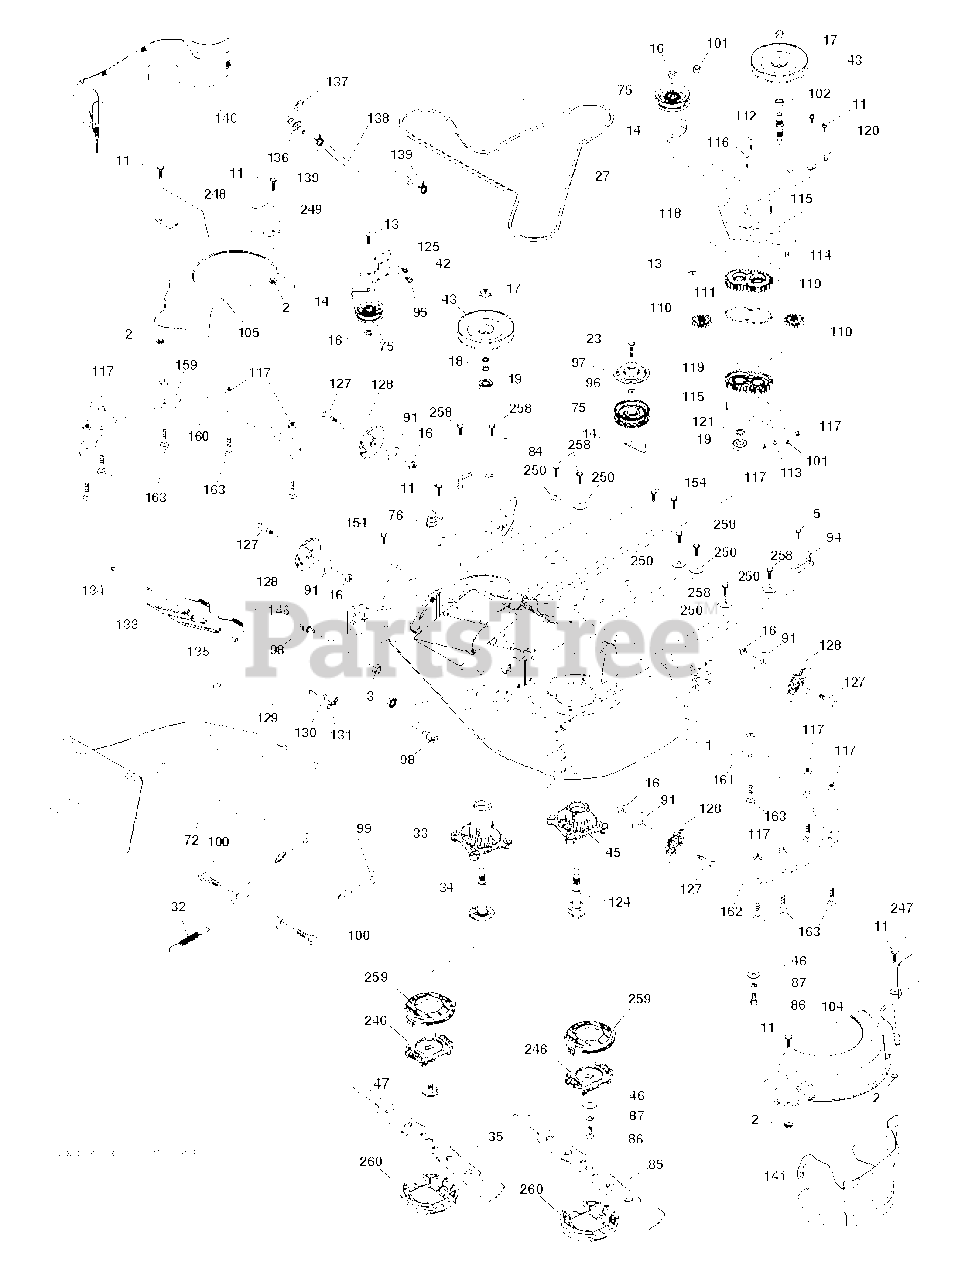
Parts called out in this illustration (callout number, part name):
1	DECK SVC 107HP.EZMUL.498
2	PALNUT 1/4
3	NUT LOCK HEX FLANGE 5/16-18
5	BOLT.5/16HEX.WHS.HD
11	SCREW.1/4-20X5/8
13	BOLT.3/8-16X1.50
14	KEEPER, BELT IDLER
16	NUT LOCK FLG 3/8-16 UNC
17	NUT.FLANGE.LOCK.TOP
18	WASHER.SPACER.MANDREL
23	SCREW LT
27	BELT BELT. ELECTRIC MOWER DRIV
32	SPRING 107CM & 97CM ELECTRIC D
33	HOUSING.MANDREL.REV.TALL.N/GRS
34	SHAFT ASM.REV.TALL.N/GREASEBL
35	BLADE.REVLTION.107CM.LHS.PT431
42	SCREW
43	PULLEY PULLEY MANDREL 5.438 PD
45	RP HOUSING.MANDREL.REV.REVS.
46	3/8 FLAT WASHER
47	SCREW.SEMS.7/16-20X1.HEX.HEAD
72	RB CHUTE 107/97 TEX GENII
75	FLAT IDLER PULLEY
76	1/2" BARB.DECK.WASHOUT.PORT
84	KEEPER KEEPER. LH MANDREL BELT
85	BLADE.REVLTION.107CM.RHS.PT431
86	BOLT.3/8-24X1.25GR8. LHTHRD
87	LOCKWASHER
91	WASHER
94	BRKT.CLUTCH.CABLE
95	SCREW, 3/8-16X3/4
96	SPACER
97	PROTECTOR
98	STUD.FASTNER.W/ANTI-ROTATE
99	ARM.SUSPENSION.MOWER.R
100	BOLT.SHOULDER
101	NUT.CROWNLOCK.9/16 -18.UNC
102	SPACER BEARING
104	COVER.MANDREL.107.RH.GEN.2
105	COVER.MANDREL.107.LH.GEN.2
110	GEAR GEAR OUTPUT
111	GASKET GASKET GEARCASE
112	SHAFT SHAFT. CRD GEARCASE ADAP
113	PLUG PLUG OIL
114	VALVE VALVE RELIEF
115	SCREW
116	BOLT.CARIGE.SS.1/4-20X1.75GR5
117	NUT T
118	ARM ARM. CLUTCHING 107 TEX CRD
119	GEARCASE GEARCASE SUBASM
120	KEEPER KEEPER. RH MANDREL BELT
121	WASHER WASHER
124	SUB.ASM.REVERSE.THREAD.REV
125	BRACKET
127	BOLT.SHOULDER.3/8-16X3-5/8.
128	WHEEL. GUAGE RALLY
129	ROD ROD. SWAY CRD GEN II
130	WASHER
131	PIN.COTTER.5/16.BOW TI
133	COVER DOOR.107 CM CRD EZ MULCH
134	PIN PIN.HINGE
135	E-RING.5/16"
136	PLUG WASHOUT PORT HOOKUP
138	107.WASHOUT.PORT.HOSE (2 2)
139	HOSE.3/8.CLAMP (2 2)
140	GUARD FRENCH 107 TEX ASSEMBLY
141	GUARD SUBASM. 107 TEX GEN 2 RH
146	SPRING SPRING: EZ MULCH DOOR
154	SCREW T-30 1/4-20 X
159	REINFORCE.PLATE.LH.FT.X431
160	REINFORCE.PLATE.LHS.BOLT.431
161	REINFORCE.PLATE.RH.FRT.X431
162	REINFORCE.PLAT.RH.SD.BLT.X431
163	BOLT
246	HOLDER BLADE REVOLUTION
247	GUARD.STEEL.CRD.MANDREL.COV.FR
248	GUARD.STEEL.CRD.MANDREL.COV.FR
249	GUARD.STEEL.CRD.MANDREL.COV.FR
258	BOLT.HEX.WASHR.HED.313-18X1.19
259	CAP.REVOLUTION.UPPER
260	CAP.REVOLUTION.LOWER
